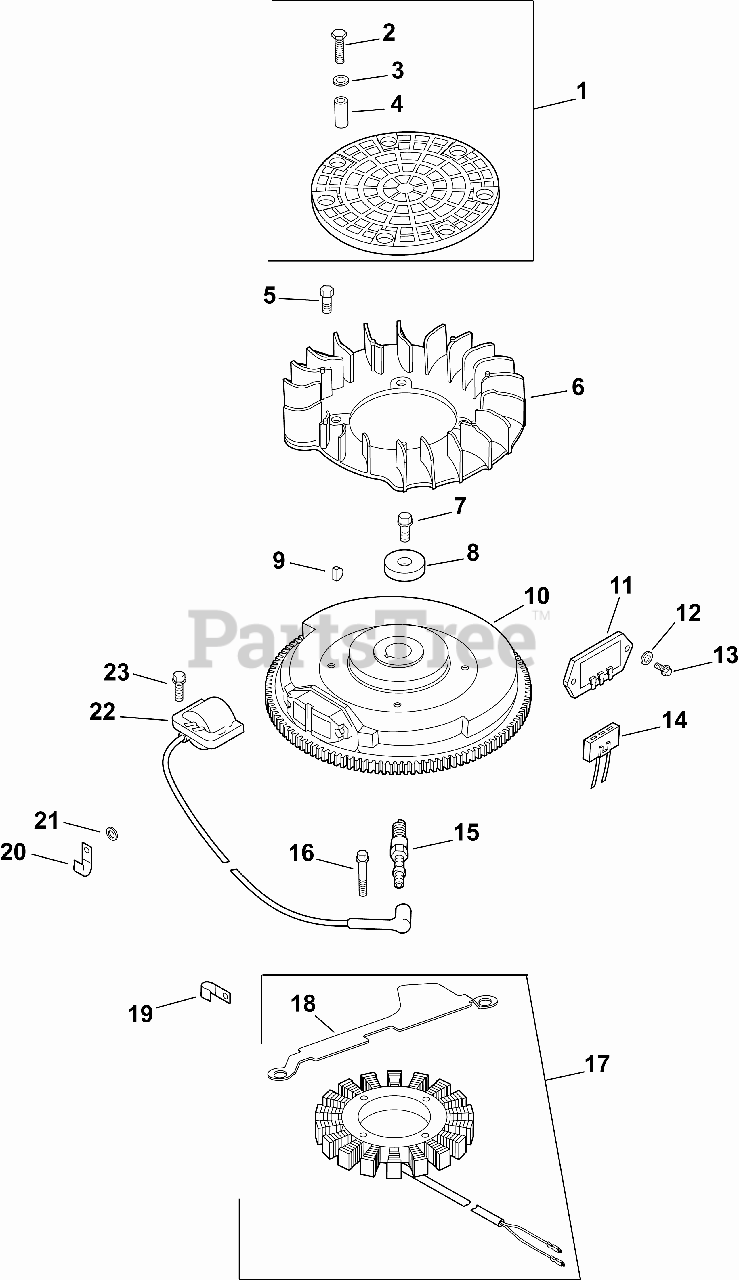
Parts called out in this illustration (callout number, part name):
1	KIT, GRASS SCREEN
2	SCREW, SLT HD CAP M4X0.7X25
3	WASHER, FLAT 3/16"
4	SPACER - DISCONTINUED
5	BOLT, SHOULDER
7	SCREW, FLG M10X1.5X45 - (#25086361S)
8	WASHER, FLAT 13/32"
9	KEY, 3/16" X 5/8"
10	FLYWHEEL, PAINTED-USE 24 025 55-S
11	REG/RECT-15 AMP (KM)-USE 41 403 10-S
12	WASHER, FLAT 1/4" (O.D. 1/2")
13	SCREW, PHL HD #11-16X7/8"
14	CONNECTOR, BODY (KM)-USE 25 155 41-S
15	PLUG, SPARK (STD)
16	SCREW, M5X0.8X25 - (#25086402S)
17	STATOR KIT - USE 237878-S
18	BRACKET, STATOR WIRE
20	CLIP, CABLE
21	WASHER, FLAT 3/16"
22	MODULE, IGNITION-USE 24 584 45-S
23	SCREW, FLG THD FRM M5X.8X20-(#25086399S)
